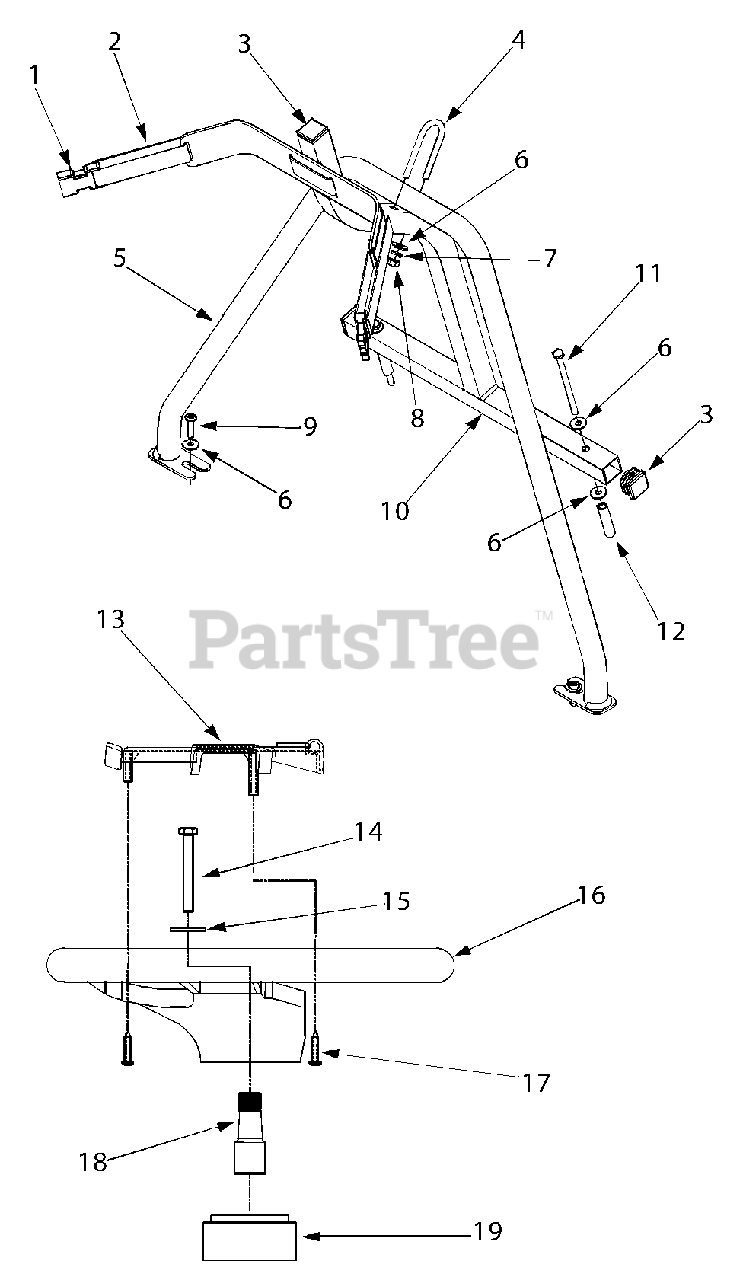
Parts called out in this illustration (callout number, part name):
1	Squeeze Release Buckle
4	U-Bolt 1/4-20 x 2.56
5	Support Assembly
6	Flat Washer .260 ID x .720 OD
7	Lock Washer 1/4
8	Hex Nut 1/4-20
9	Machine Screw 1/4-20 x 1.0
10	Frame Assembly
11	Hex Cap Screw 1/4-20 x 3.75
12	Spacer .281 ID x .438 OD
13	Steering Wheel Cap
14	Hex Cap Screw 5/16-18 x 2.50 Patch
15	Flat Washer .344 ID x 1.125 OD
16	Steering Wheel
17	Screw #10-12 x 1.0
18	Steering Wheel Adapter
19	Column Spacer
